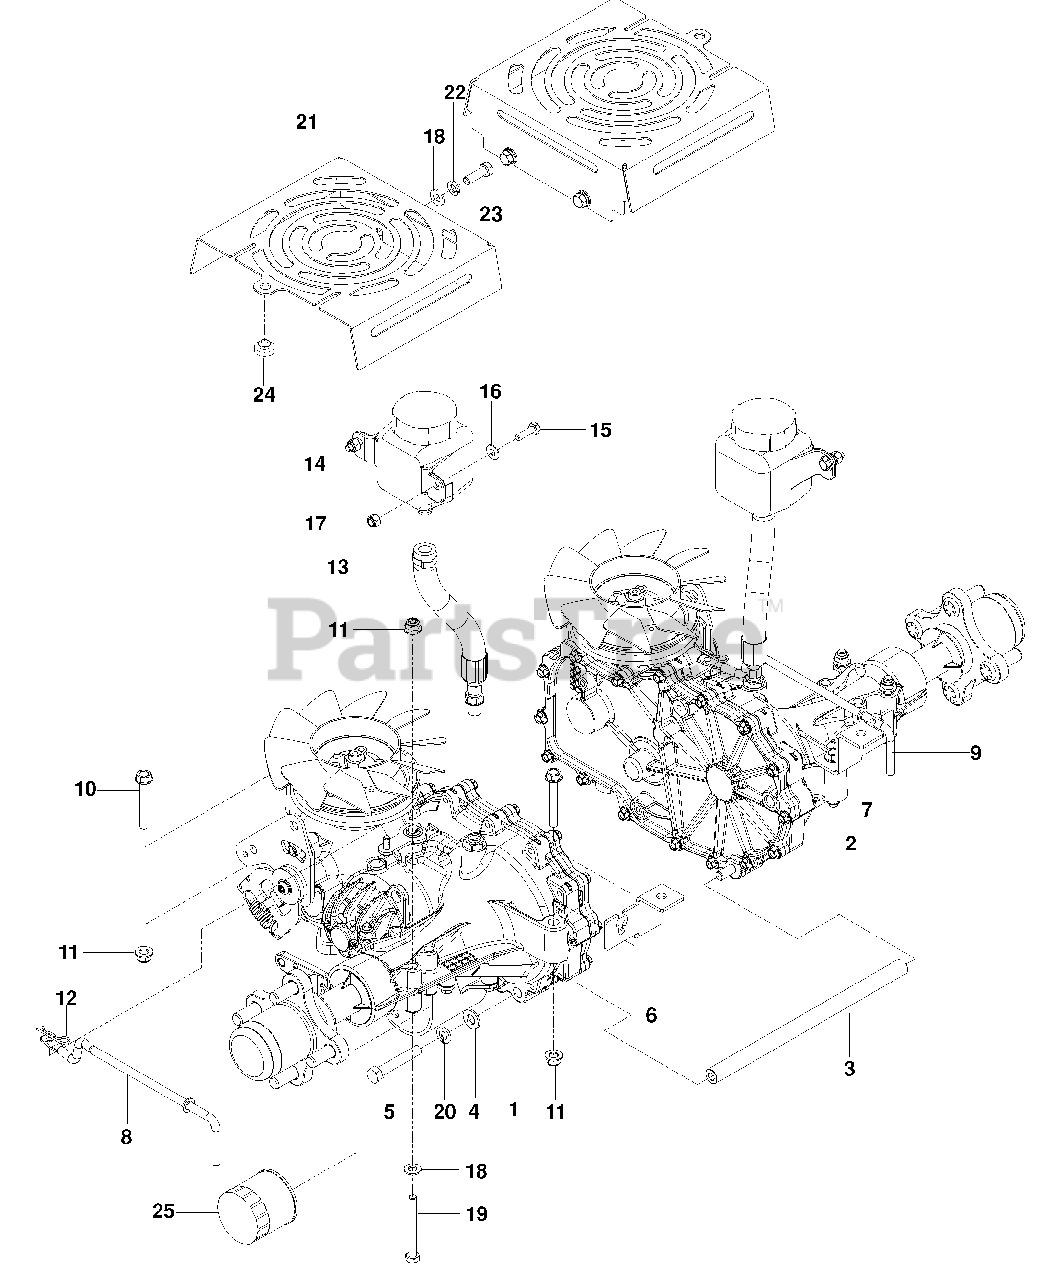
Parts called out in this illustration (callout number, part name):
1	TRANS, ZT-3400, LT
2	TRANS, ZT-3400, RT
3	TUBE, SPACER, 3400
4	WASHER, 3/8 SAE FLT
5	HCS 3/8-16 x 2 1/2 GR8
6	BRACKET, TRANS, LT
7	BRACKET, TRANS, RT
8	LINKAGE, LEFT BYPASS
9	LINKAGE, RIGHT BYPASS
10	HHFS 5/16-18 x 2 1/4
11	NUT 5/16-18 HEX FLG NYLOC
12	HAIRPIN COTTER
13	HOSE, EXPANSION
14	TANK, EXPANSION
15	HCS 1/4-20 x 7/8
16	WASHER 1/4 FLAT SAE
17	NUT 1/4-20 HEX NYLOC
18	WASHER 5/16 SAE FLAT
19	HCS 5/16-18 x 2 3/4
20	WASHER 3/8 SPLT LK
21	COVER, FAN
22	WASHER 5/16 SLW
23	HCS 5/16-18 x 1
25	FILTER, HYDRO
